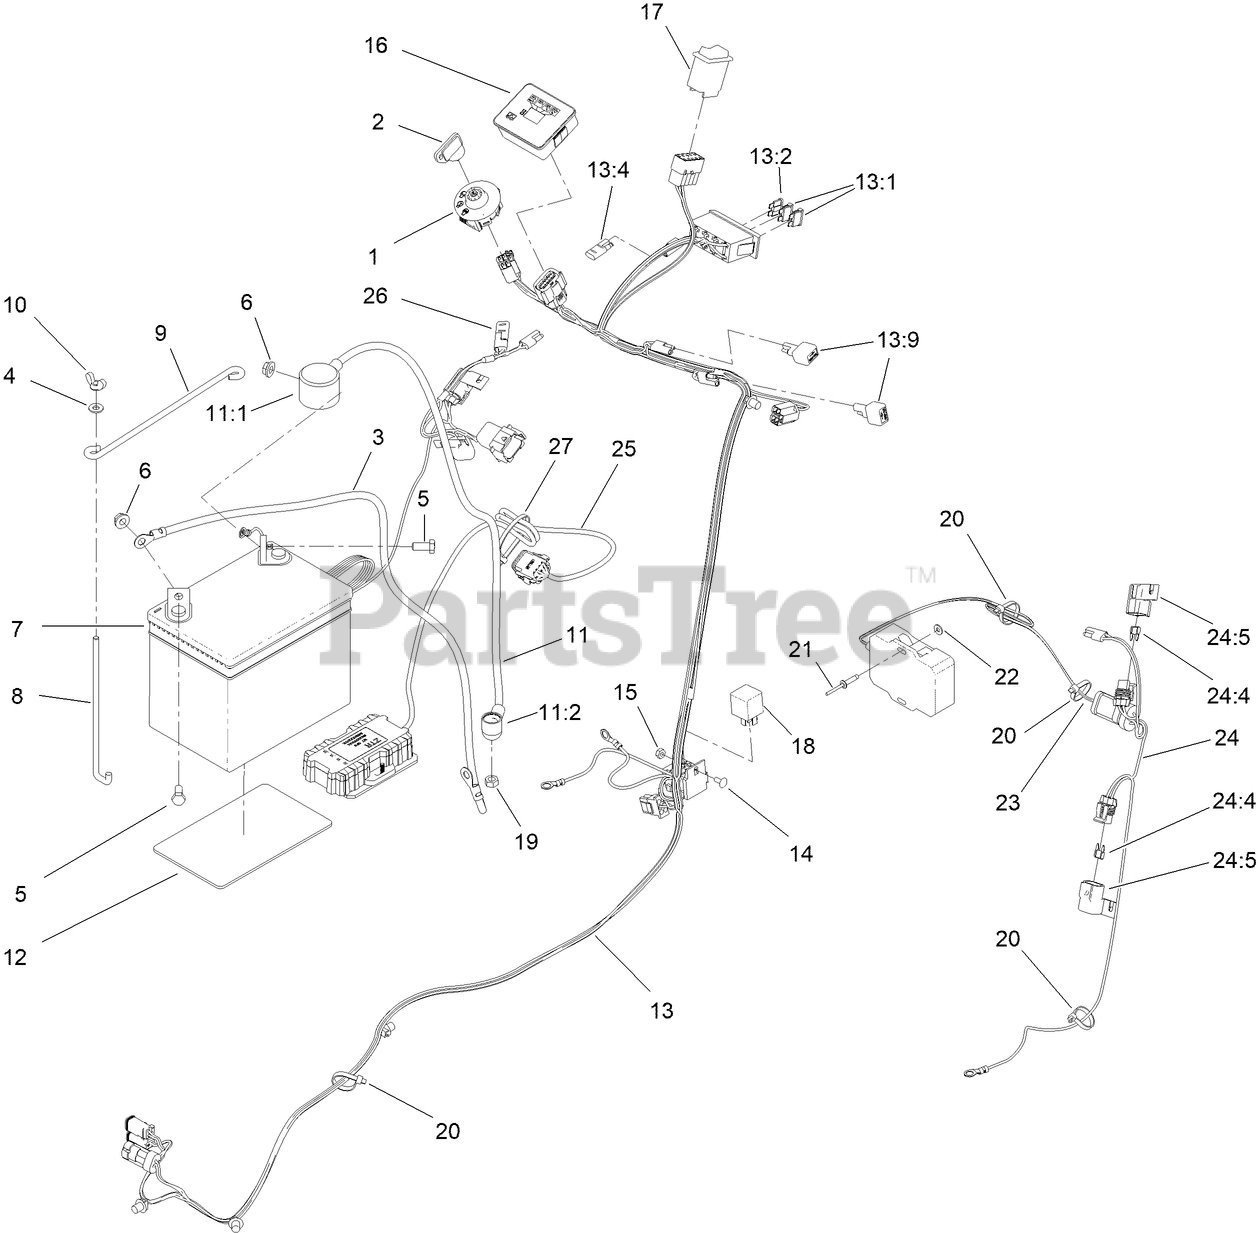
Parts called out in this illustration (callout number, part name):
1	SWITCH-IGNITION
2	KEY-IGNITION
3	CABLE-BATTERY, NEGATIVE
4	WASHER-FLAT
5	SCREW-HH
6	NUT-HF
7	BATTERY-12V, 350CCA
8	POST-BATTERY
9	ROD-HOLD DOWN, BATTERY
10	NUT-WING
11	POSITIVE BATTERY CABLE ASM
11:1	INSULATOR-BATTERY
11:2	INSULATOR-SOLENOID
12	PAD-SKID, ANTI
13	HARNESS-WIRE
13:1	FUSE-BLADE, 15 AMP
13:2	FUSE-BLADE, 7.5 AMP
13:4	CAP-PLUG
14	BOLT-CARR
15	NUT-LOCK, NI
16	MODULE, HOUR METER
17	SWITCH-ROCKER, 2 POLE
19	NUT-HEX
20	TIE-CABLE
21	RIVET-POP
22	WASHER-PLAIN
23	GPS ASM
24	HARNESS-WIRE, GPS
24:4	FUSE-MINI BLADE, 5 AMP
24:5	COVER-FUSE, SINGLE
25	M7L-LITE ZTR KIT ASM
26	HARNESS-WIRE, MACHINE ZTR
27	TIE-CABLE
